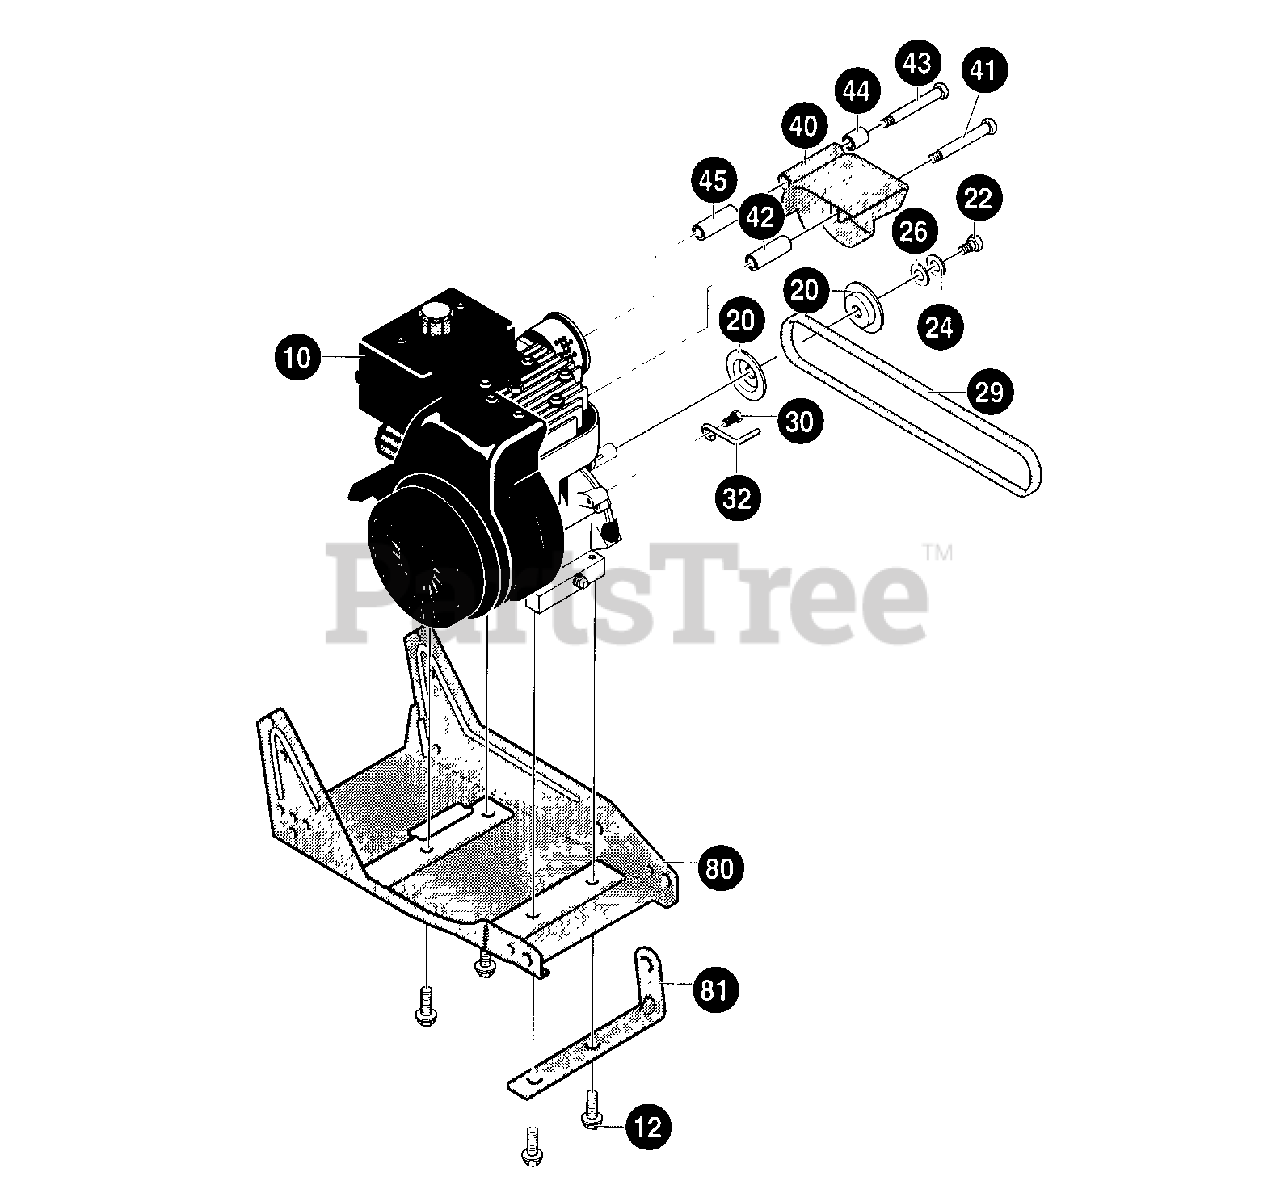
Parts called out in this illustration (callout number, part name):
12	Screw, 3/8-16 x 1.00
20	Pulley, Half V3L
22	Screw, 5/16-24 x 1.00 HHC
24	Washer, SPTLK .328 x .60 x .09
26	Flatwasher .333 x 87 x .119
29	Belt, V4L 32.60LG
30	Screw and Washer Assy
32	Belt Guide
40	Cover, Engine Pulley
41	Screw, 5/16-24 x 3.00
42	Spacer, Sleeve .335 x.431 x 2.50
43	Screw, 5/16-24 x 3.75
44	Spacer,.322 ID 562 OD
45	Spacer, Sleeve .335 x .431 x 2.50
80	Frame, Assy Edger
